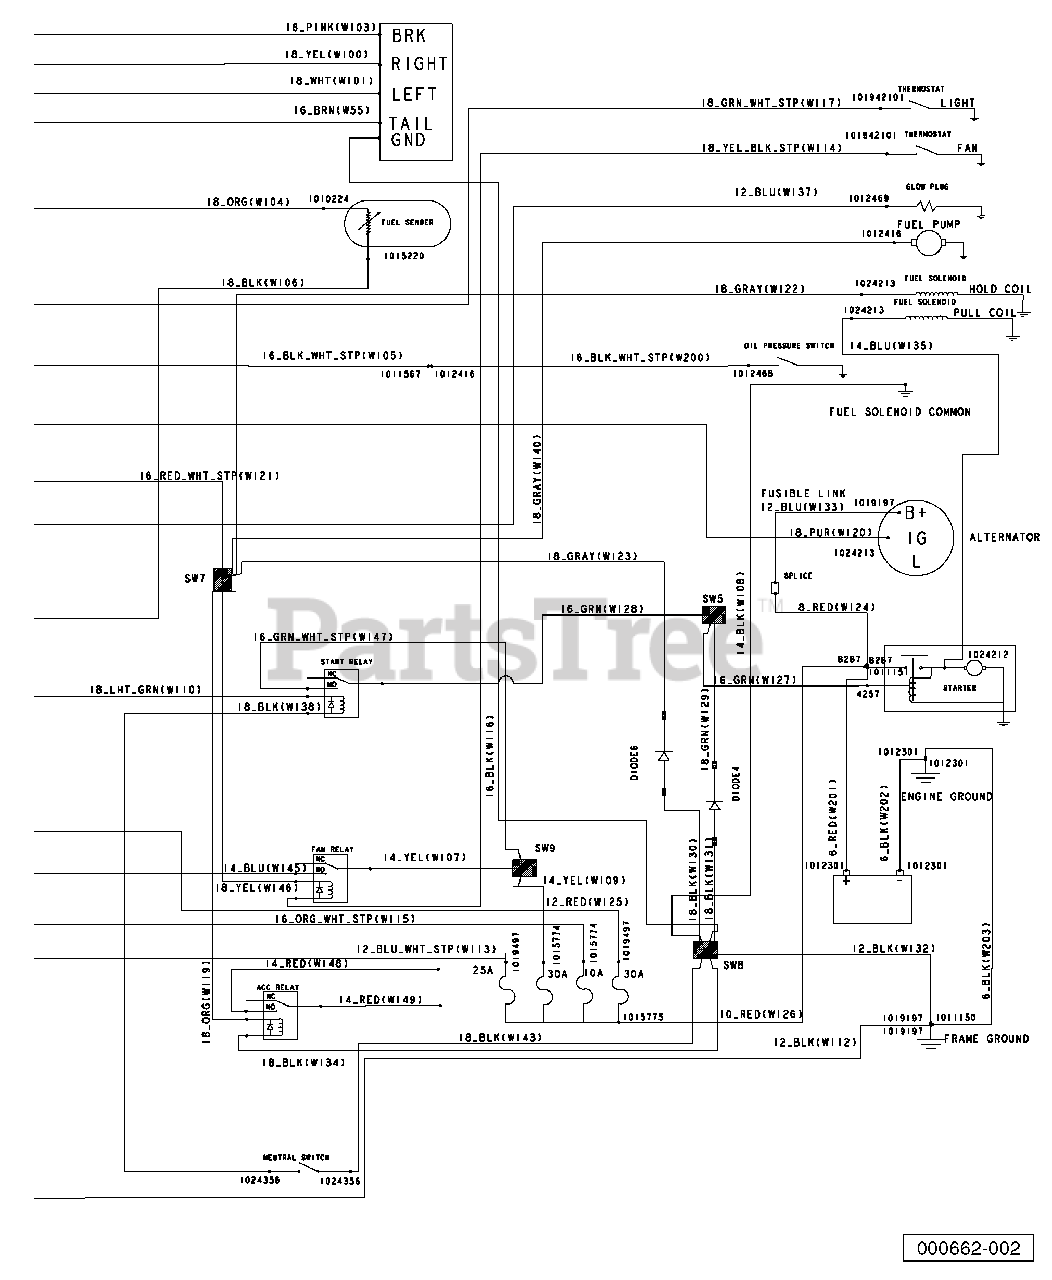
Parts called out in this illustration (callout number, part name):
1	Diode, General Purpose, 6.0a
2	Harness, AWD, Kawasaki
3	Asm, Switch, Limit, Awd
